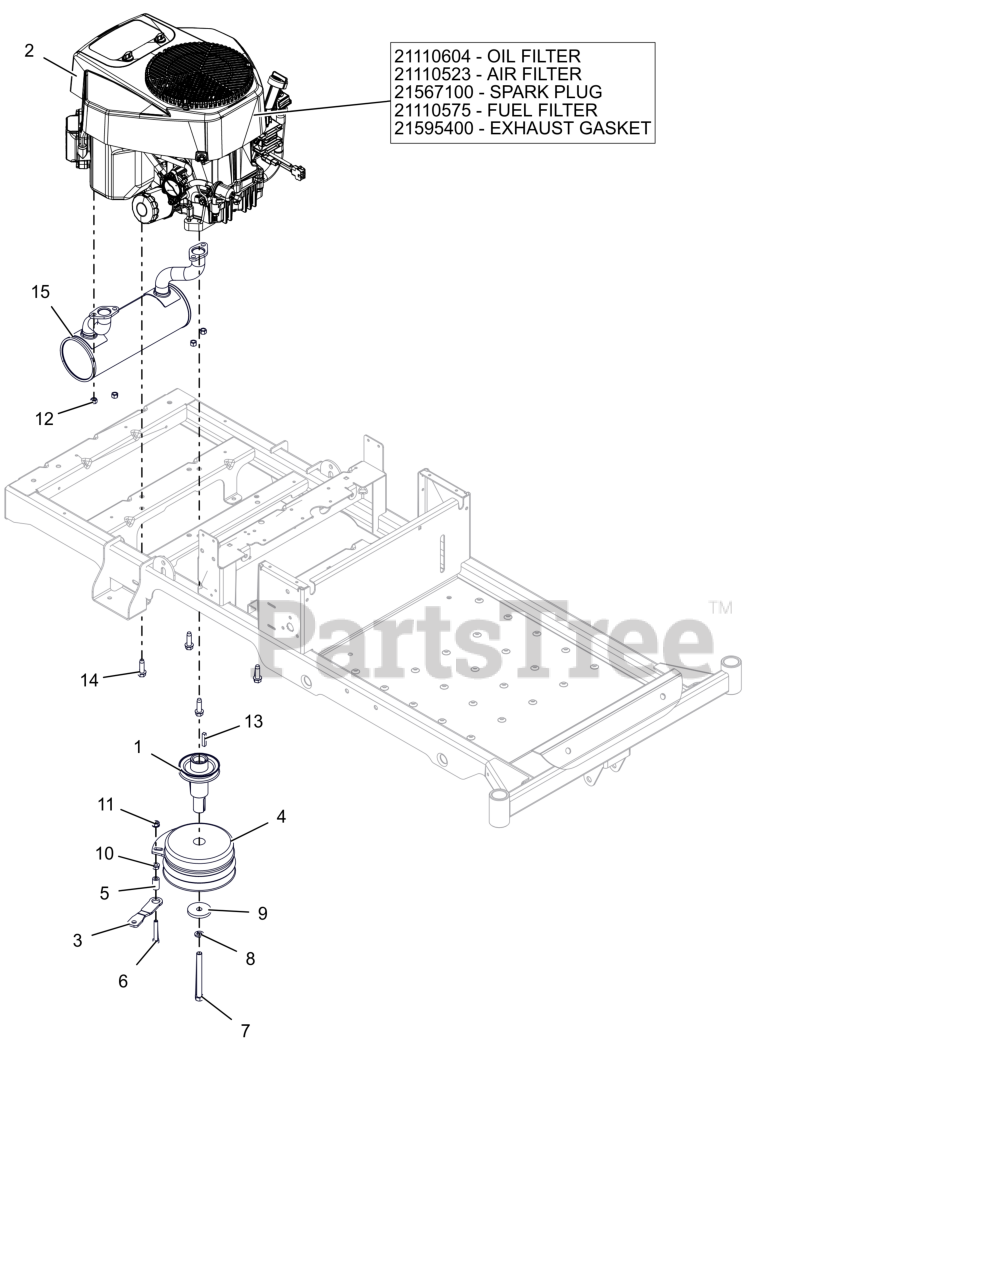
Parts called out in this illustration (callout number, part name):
1	WLDMT, CRANKSHAFT EXTENSION
2	ENGINE, ARIENS 635cc
2	OIL FILTER
2	AIR FILTER
2	PLUG, SPARK
2	FUEL FILTER
2	EXHAUST GASKET
3	BRKT, CLUTCH
4	CLUTCH, 105 FT*LB MONO POLE
5	SPACER, RUBBER 5/16 IDX1.0 LG
6	BLT, HEX .31-18X2.00 G5 ZCC
7	BLT, HEX .44-20X4.50 G8 ZCC NT
8	WSHR, LK-REG .438X.109 ZCC
9	WSHR, FLT .469X2.00X.250 ZCC
10	NUT,SPNLK-FLG .31-18 G5 ZCC
11	NUT,LK-CTR-FLG .31-18 GF ZCC
12	NUT-LK-TOP-FLG M8 ZCC
13	KEY-SQ .25 X 1.25 X .25 SAE
14	SCR,TAP .375-16X1.25HWH TR ZCC
15	MUFFLER, LONCIN 635CC
